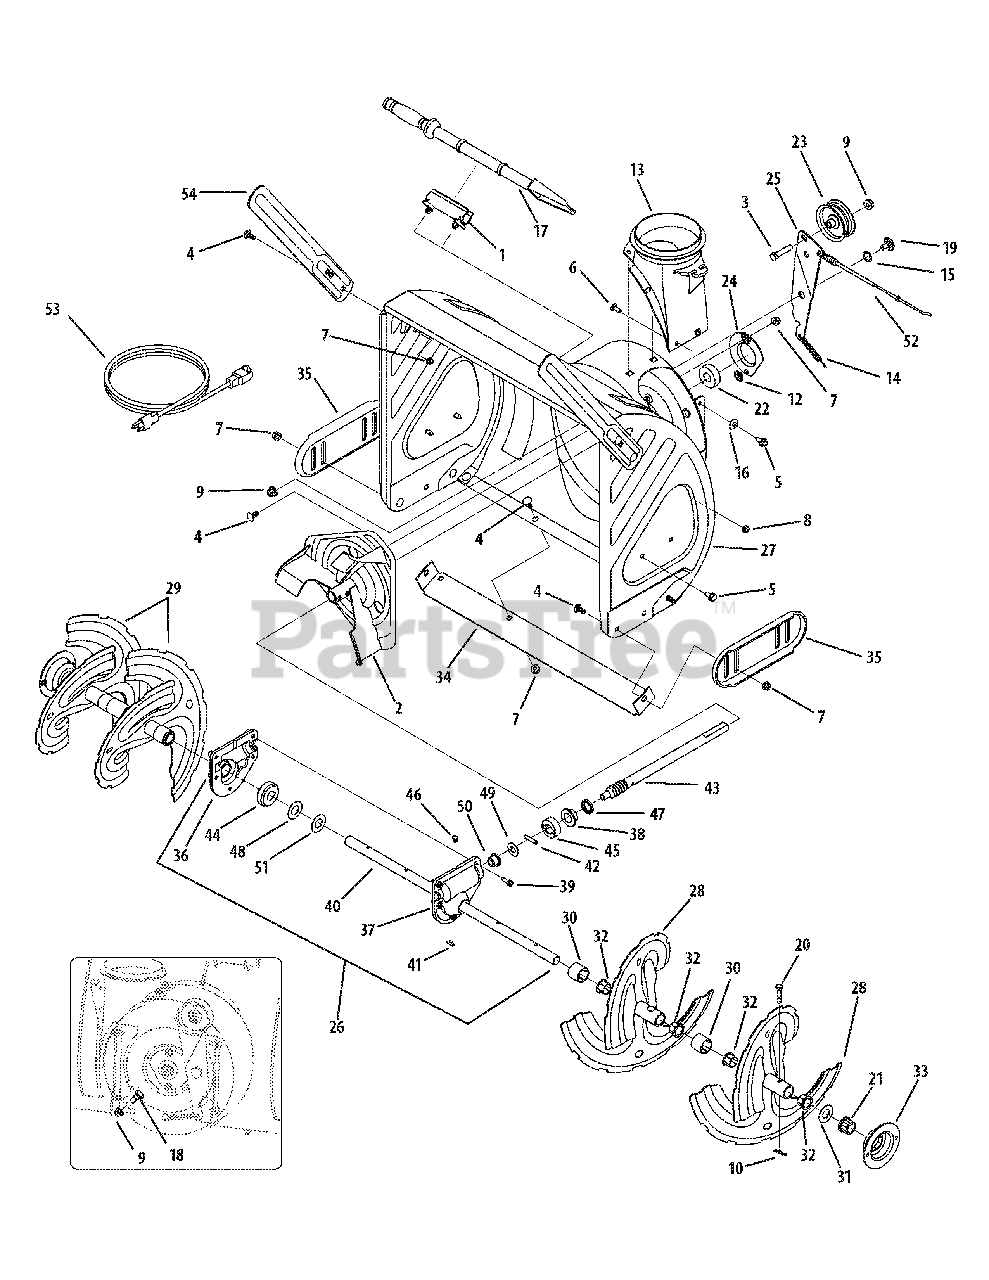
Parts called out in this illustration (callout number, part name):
1	Clean-out Tool Bracket
3	Hex Screw, 3/8-16, 1.75, Gr5
4	Carriage Bolt, 5/16-18, .750 Gr1
5	Screw, 5/16-18, 0.625
6	Carriage Screw, 1/4-20, .750, Gr5
7	Flange Lock Nut, 5/16-18, Nylon
8	Flange Lock Nut, 1/4-20, Nylon
9	Flange Lock Nut, 3/8-16, Nylon
10	Bow-tie Cotter Pin
11	Cable Tie, 3/16 x .05 x 7.4
13	Chute Adapter
14	Extension Spring, .38 OD x 3.6
15	Wave Washer, .625 x .885 x .015
16	Bell Washer, .340 x .872 x .060
17	Clean-out Tool
18	Shoulder Screw, .498 x .34, 3/8-16
19	Shoulder Screw, .625 x .17, 3/8-16
20	Shear Pin, .25 x 1.50
21	Hex Flange Bearing x .75 ID
22	Ball Bearing, .75 ID x 1.85 OD
23	Idler Pulley, 2.75 OD
24	Bearing Housing, 1.85 ID
26	Auger Gearbox Assembly, 30"
30	Spacer, 1.25 OD x .75 ID x 1.00
31	Flat Washer, .76 x 1.49 x .06
32	Flange Bushing, .80 ID x .91 OD
36	Auger Housing, RH Reduced
37	Auger Housing, LH Reduced
38	Flange Bearing, .75 x 1.0 x .59
39	Self-tapping Screw, 1/4-20, 0.750
40	Auger Axle, 30"
41	Hi-pro Key, 3/16 x 5/8
42	Dowel Pin, .25 OD x 1.2
43	Worm Shaft, .75 OD
44	Worm Gear, 20T
45	Thrust Collar
46	Plug, 1/4 x .437
47	Oil Seal, .75 x 1 x .131
48	Flat Washer, .760 ID x 1.5 OD
49	Flat Washer, .51 x 1.12
50	Flange Bearing, .75 x 1.0 x .925
51	Spacer, 1.25 x .75 x 3/16
52	Auger Clutch Cable, 47.23"
53	Extension Cord, 110V, 3-Prong
